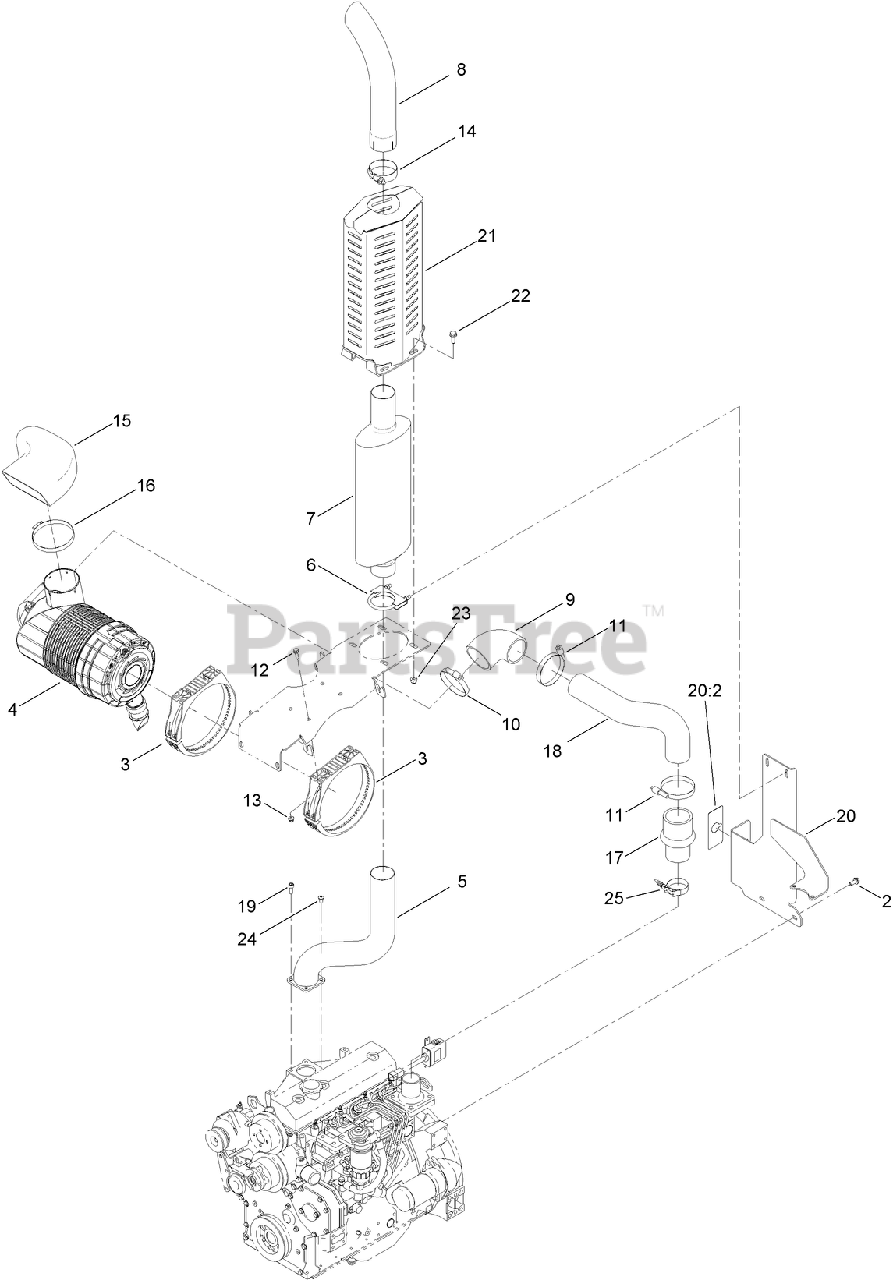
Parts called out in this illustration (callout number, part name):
2	SCREW-HHF
3	BAND-MOUNTING, AIR CLEANER
4	AIR CLEANER ASM
5	TUBE-EXHAUST
6	BOLT-U, CLAMP
7	MUFFLER-VERTICAL, OVAL
8	EXHAUST-STACK
9	CONNECTOR-AIR INTAKE
10	CLAMP-TORQUE, CONSTANT
11	CLAMP-TORQUE, CONSTANT
12	SCREW-HHF
13	NUT-LOCK, HHF
14	CLAMP-MUFFLER
15	INTAKE-Air
16	CLAMP-HOSE, WORM GEAR (HEAVY DUTY)
17	CONNECTOR-Air Intake
18	TUBE-Air Intake
19	SCREW-HSH
20	MUFFLER SUPPORT MOUNT ASM
20:2	DECAL-BATTERY DISCONNECT
21	SHIELD-EXHAUST
22	SCREW-HHF
23	NUT-LOCK, NI
24	SCREW-HSH
25	CLAMP-HOSE
